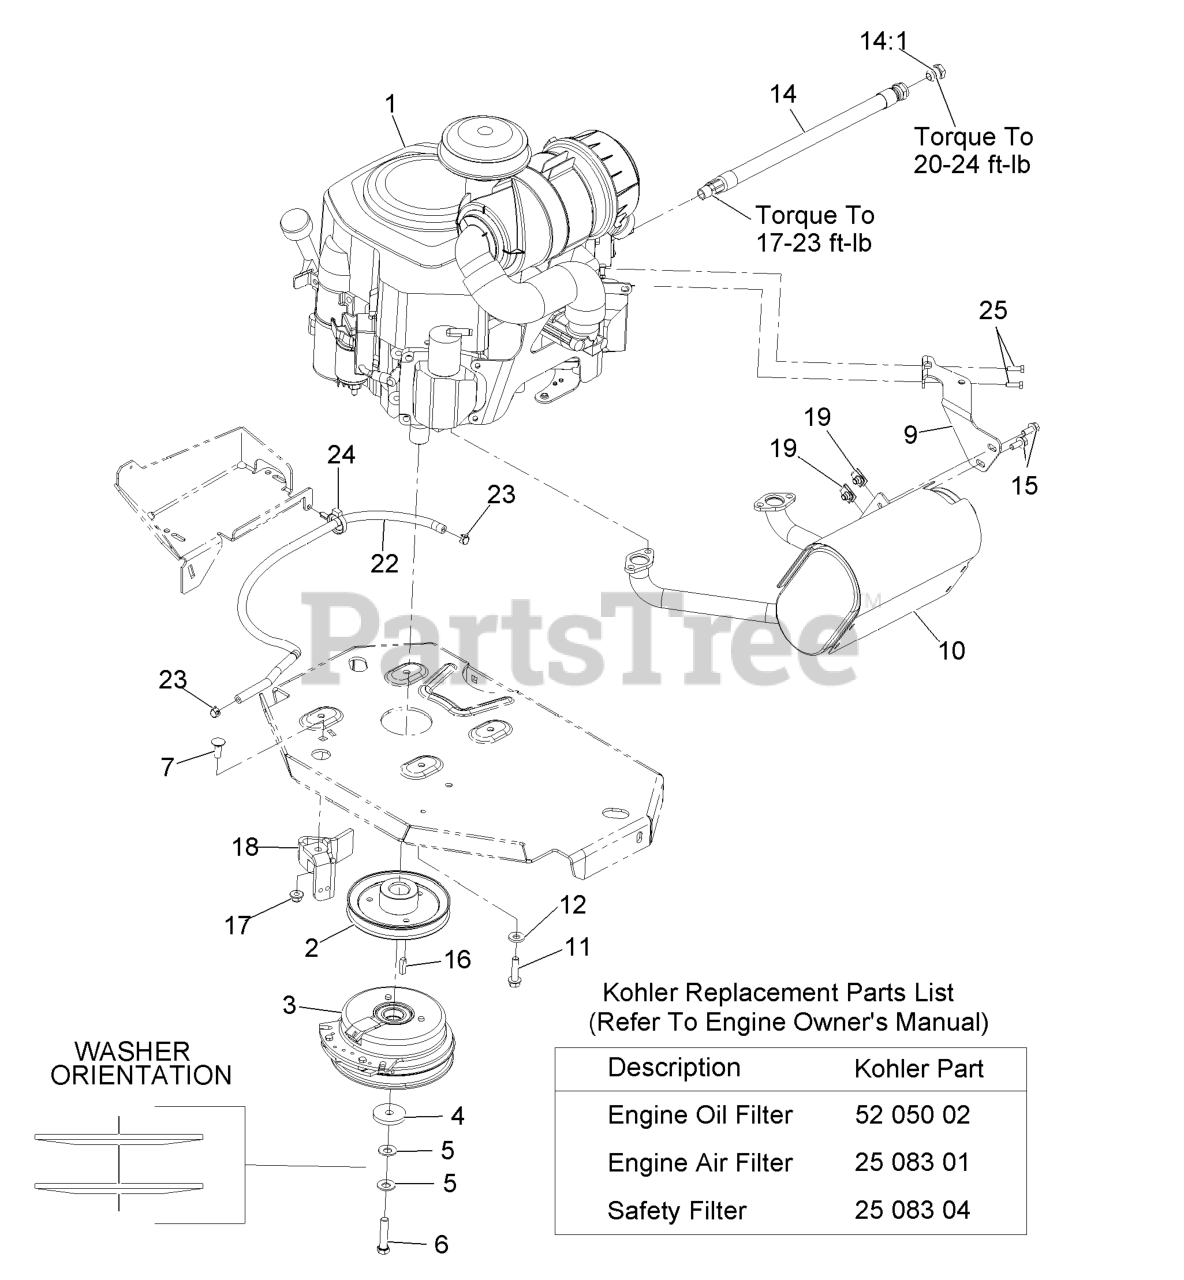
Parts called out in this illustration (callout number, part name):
1	Engine,Koh 27hp Hd
2	SHEAVE
3	CLUTCH KIT
4	WASHER-CLUTCH
5	WASHER-SPRING
6	SCREW-HH W/LOCTITE
7	SCREW-CARR
9	MUFFLER BRACKET KIT
11	SCREW-HWH
12	WASHER-BELLEVILLE
15	SCREW-HHF
17	NUT-HF, NI
18	CLUTCH-ANCHOR
22	HOSE-FUEL
23	CLAMP-HOSE
24	CLAMP-HOSE
25	SCREW-HH M6-1 X 20Mm W/Patch
